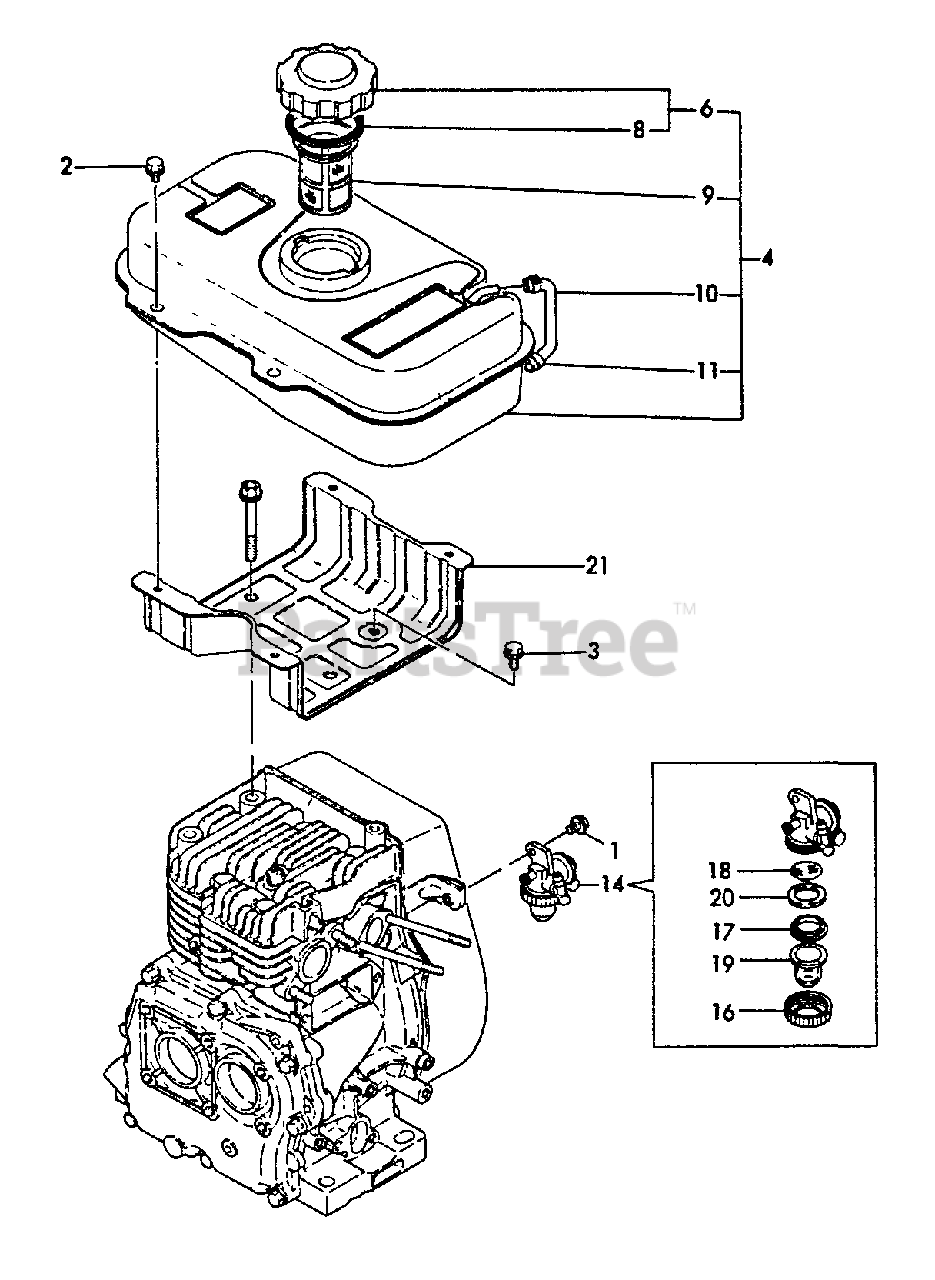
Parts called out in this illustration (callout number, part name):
1	BOLT - 6×8 -- PLATED
2	BOLT - 6×10 -- PLATED
3	BOLT - 6×8 -- PLATED
4	FUEL TANK ASSY
6	CAP ASSY
8	GASKET
9	STRAINER, FUEL
10	PIPE, GAUGE
11	CLAMP, HOSE - 9
14	COCK ASSY, FUEL
16	RETAINER
17	GASKET
18	FILTER, FUEL
19	BOWL, STRAINER
20	PLATE
21	BRACKET, FUEL TANK
